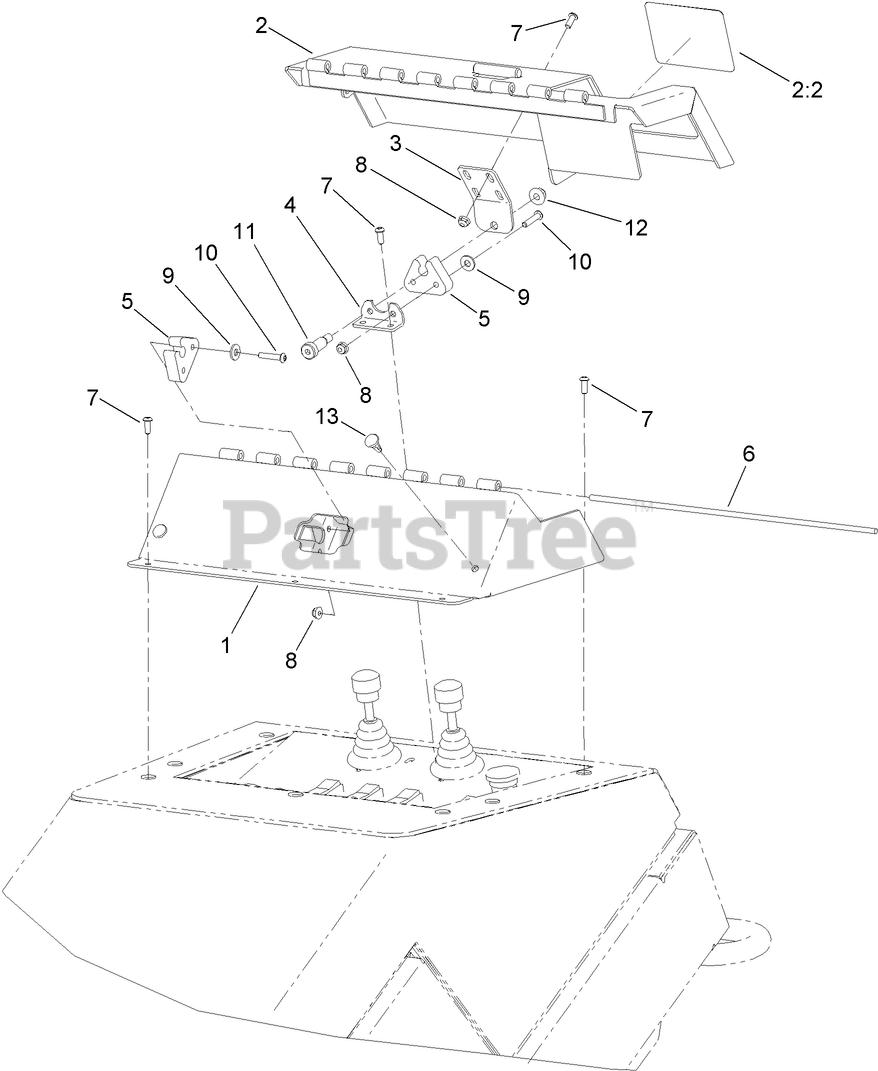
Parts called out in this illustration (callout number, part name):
1	COVER-STATIONARY
2	MOVEABLE COVER ASM
2:2	DECAL-CONTROL COVER
3	BRACKET-COVER
4	BRACKET-COVER
5	LATCH-CLIP, COVER
6	PIN-HINGE
7	SCREW-HSBH
8	NUT-HEX, FLANGE
9	WASHER-FLAT
10	SCREW-HSBH
11	BOLT-SHOULDER
12	NUT-HF, NI
13	CLIP-ARROW, NYLON
